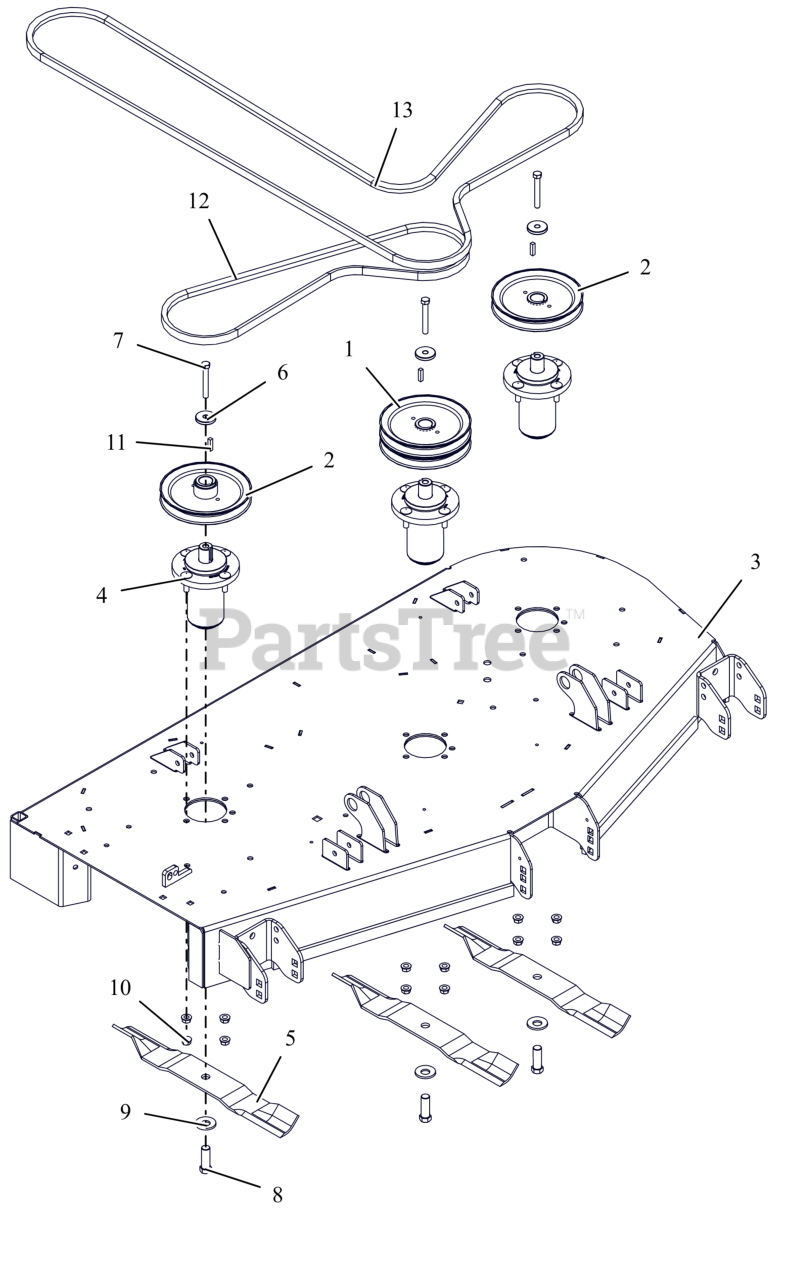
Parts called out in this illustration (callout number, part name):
1	PULLEY, DOUBLE-1"ID X 6.75"OD
2	PULLEY, V-1" ID X 6.75" OD
3	WLDMT, 52 SIDE DISCH DECK CE (ORANGE)
4	ASM, MAINT FREE ALUM SPINDLE
5	BLADE, 18"
6	RETAINER, SHEAVE
7	BLT, HEX .38-16X2.75 G8 ZCC
8	BLT, HEX .62-18X1.75 G8 ZCC
9	WSHR-BLVL .669X1.535X.138
10	NUT-LK-CTR-FLG .375-16 GF ZCC
11	KEY, SQ .25X.25X1.00 RC 40-50
12	V-BELT, B-COGGED
13	V-BELT, HB SECTION
